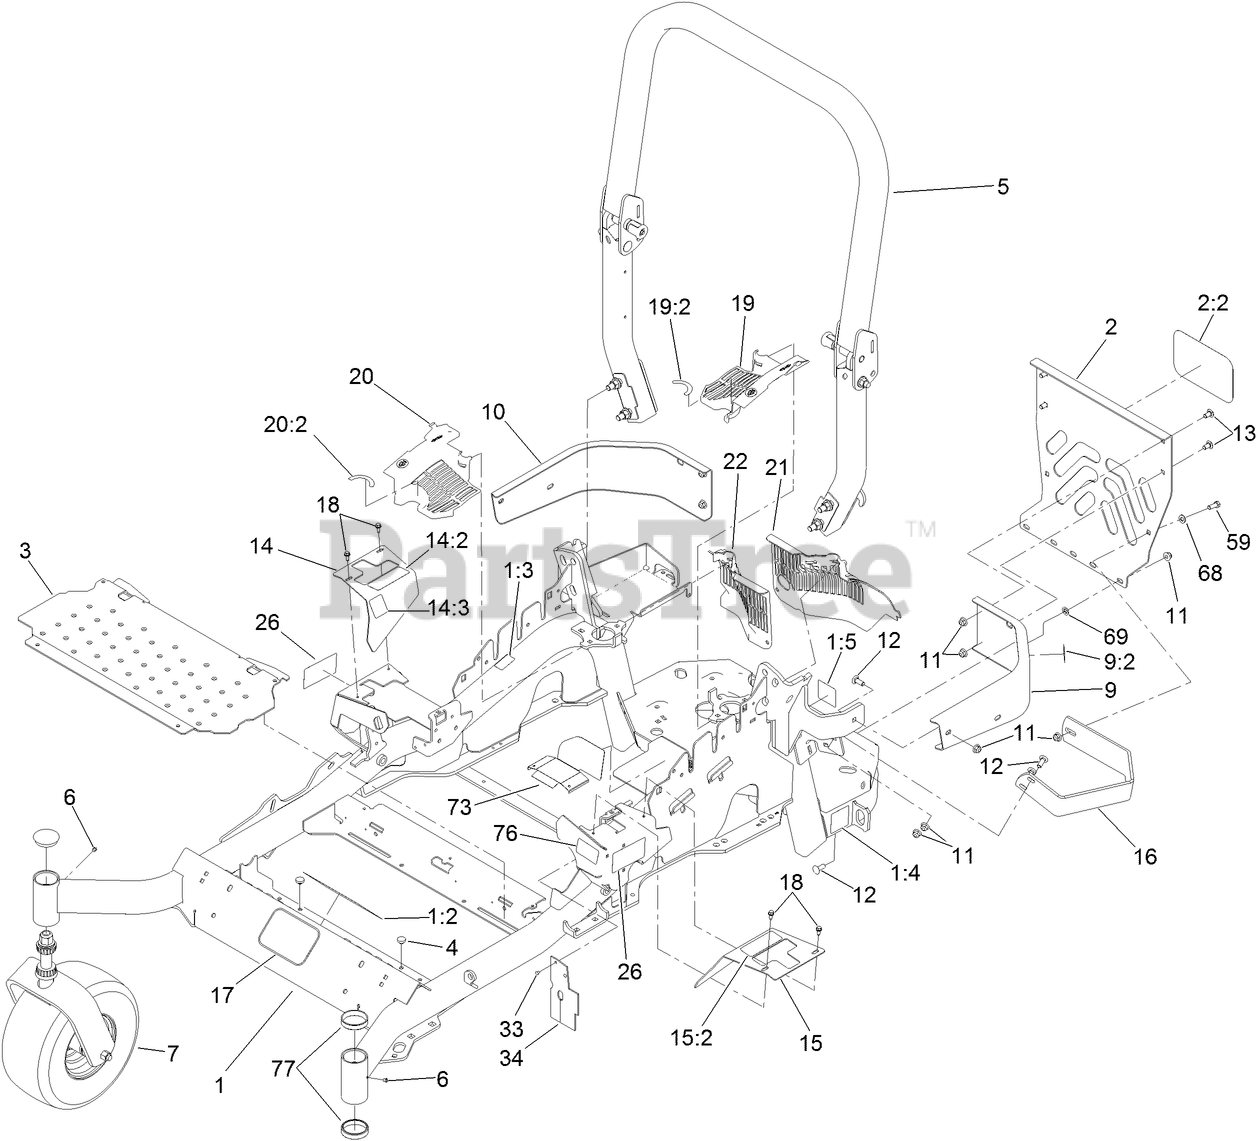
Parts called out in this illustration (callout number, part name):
1	MAINFRAME ASM
1:2	DECAL-SLOPE
1:3	DECAL-CAUTION
1:4	DECAL-BELT DRIVE
1:5	DECAL-SPARK ARRESTER
2	REAR GUARD ASM
2:2	DECAL
3	FLOORPAN
4	BUMPER
5	ROPS ASM
7	Caster Wheel ASM
9	LH BUMPER ASM
9:2	DECAL-CAUTION
10	BUMPER-RH
11	NUT-HF, NI
12	SCREW-CARR
13	SCREW-CARR
14	RH MOTION CONTROL COVER ASM
14:2	DECAL-MOTION CONTROL
14:3	DECAL-PARK BRAKE
15	LH MOTION CONTROL COVER ASM
15:2	DECAL-MOTION CONTROL
16	GUARD-MUFFLER
17	DECAL
18	SCREW-HWH
19	LH HYDRO GUARD ASM
19:2	DECAL-HYDRO OIL
20	RH HYDRO GUARD ASM
20:2	DECAL-HYDRO OIL
21	GUARD-HYDRO REAR, LH TRIM
22	GUARD-HYDRO, REAR (RH)
33	RIVET-POP
34	DEFLECTOR-AIR FLOW
59	SCREW-HH
68	WASHER-FLAT
69	NUT-PUSH
73	GUARD-EXHAUST
76	DECAL-FUEL FILL
77	CUP-BEARING
